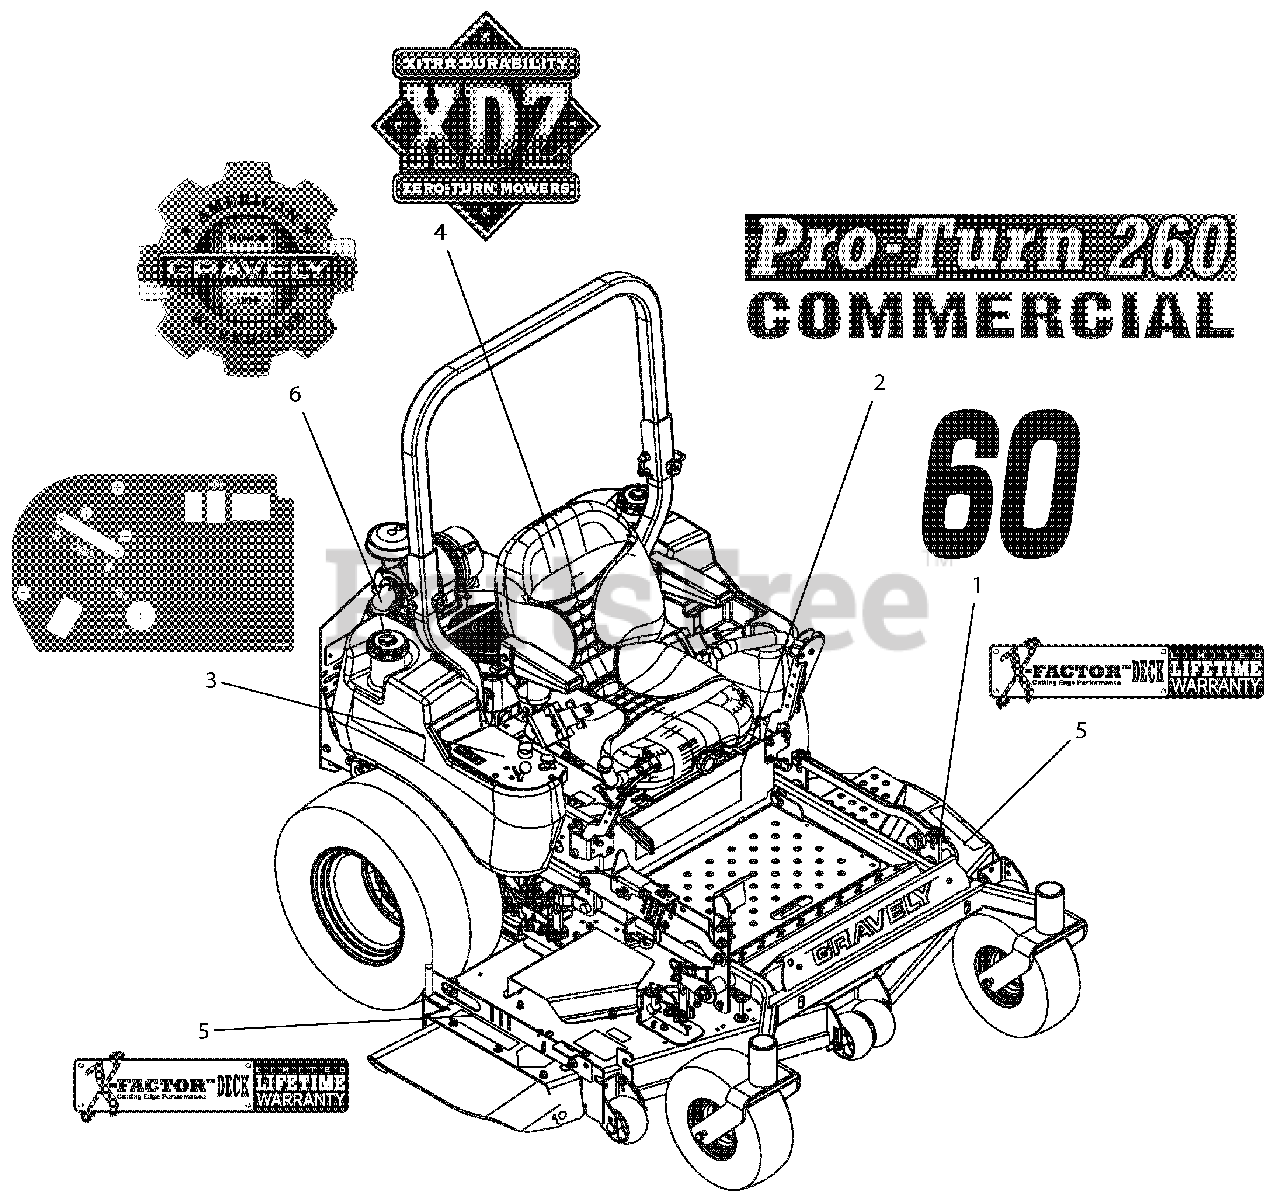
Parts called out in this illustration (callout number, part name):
1	DECAL, 60"
2	DECAL, PROTURN 260
3	DECAL, CONTROL PANEL EFI
4	DECAL, XDZ
5	DECAL, X-FACTOR DECK
6	DECAL, GRAVELY HERITAGE-LARGE
